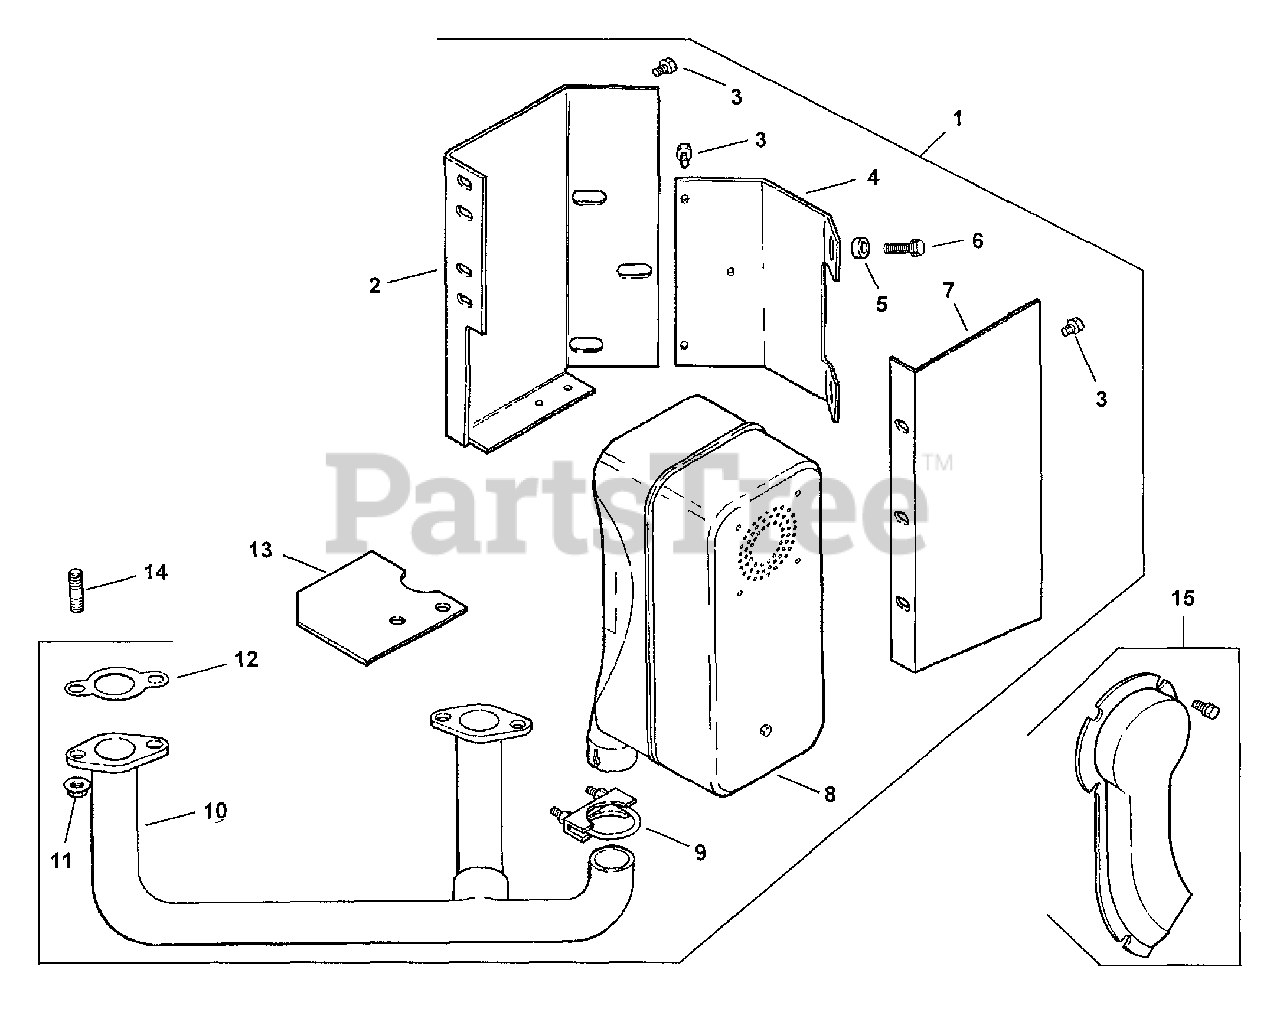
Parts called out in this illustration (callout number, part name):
1	KIT, MUFFLER MOUNTING
2	BRACKET, MUFFLER
3	SCREW - USE M-645016
4	BRACKET, MUFFLER
6	SCREW - USE M-651030
7	DEFLECTOR, EXHAUST
8	MUFFLER USE 24 067 127-S
9	CLAMP, MUFFLER
10	MANIFOLD, EXHAUST
11	NUT - USE M-841080
13	DEFLECTOR - USE 24 265 09
14	STUD - USE M-829033
